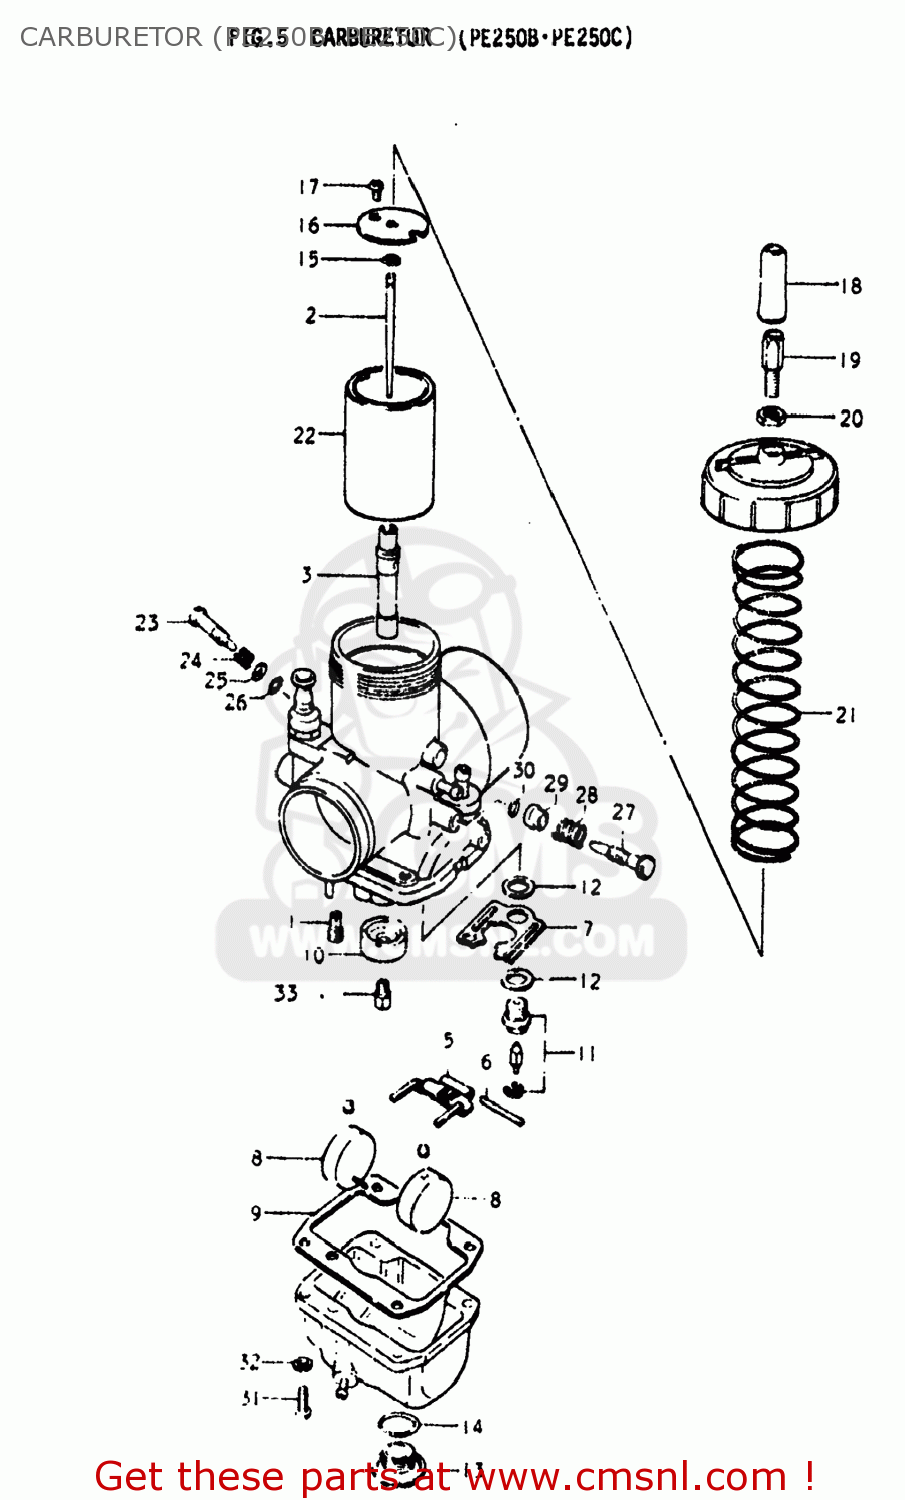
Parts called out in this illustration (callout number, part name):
0	CARBURETOR ASSEMBLY
1	JET
2	NEEDLE JET
3	JET,NEEDLE
4	JET
5	ARM,FLOAT
6	PIN,FLOAT
7	PLATE
8	FLOAT
9	GASKET,FLOAT CAHMBER (NAS)
10	RING
11	VALVE ASSEMBLY,NEEDLE
12	GASKET,MAIN JET HOLDER (NAS)
13	SCREW,GUIDE
14	O RING,DRAIN PLUG
15	CLIP
16	CLIP
17	SCREW
18	CAP,CABLE ADJUSTER
19	ADJUSTER,CABLE
20	NUT
21	SPRING,THROTTLE VALVE RETURN
22	VALVE,THROTTLE
23	SCREW,PILOT AIR
24	SPRING
25	WASHER,PILOT AIR SCREW
26	O RING
27	SCREW,THROTTLE STOP
28	SPRING,THROTTLE STOP
29	COVER
30	O-RING
31	SCREW
32	LOCK WASHER
33	JET
